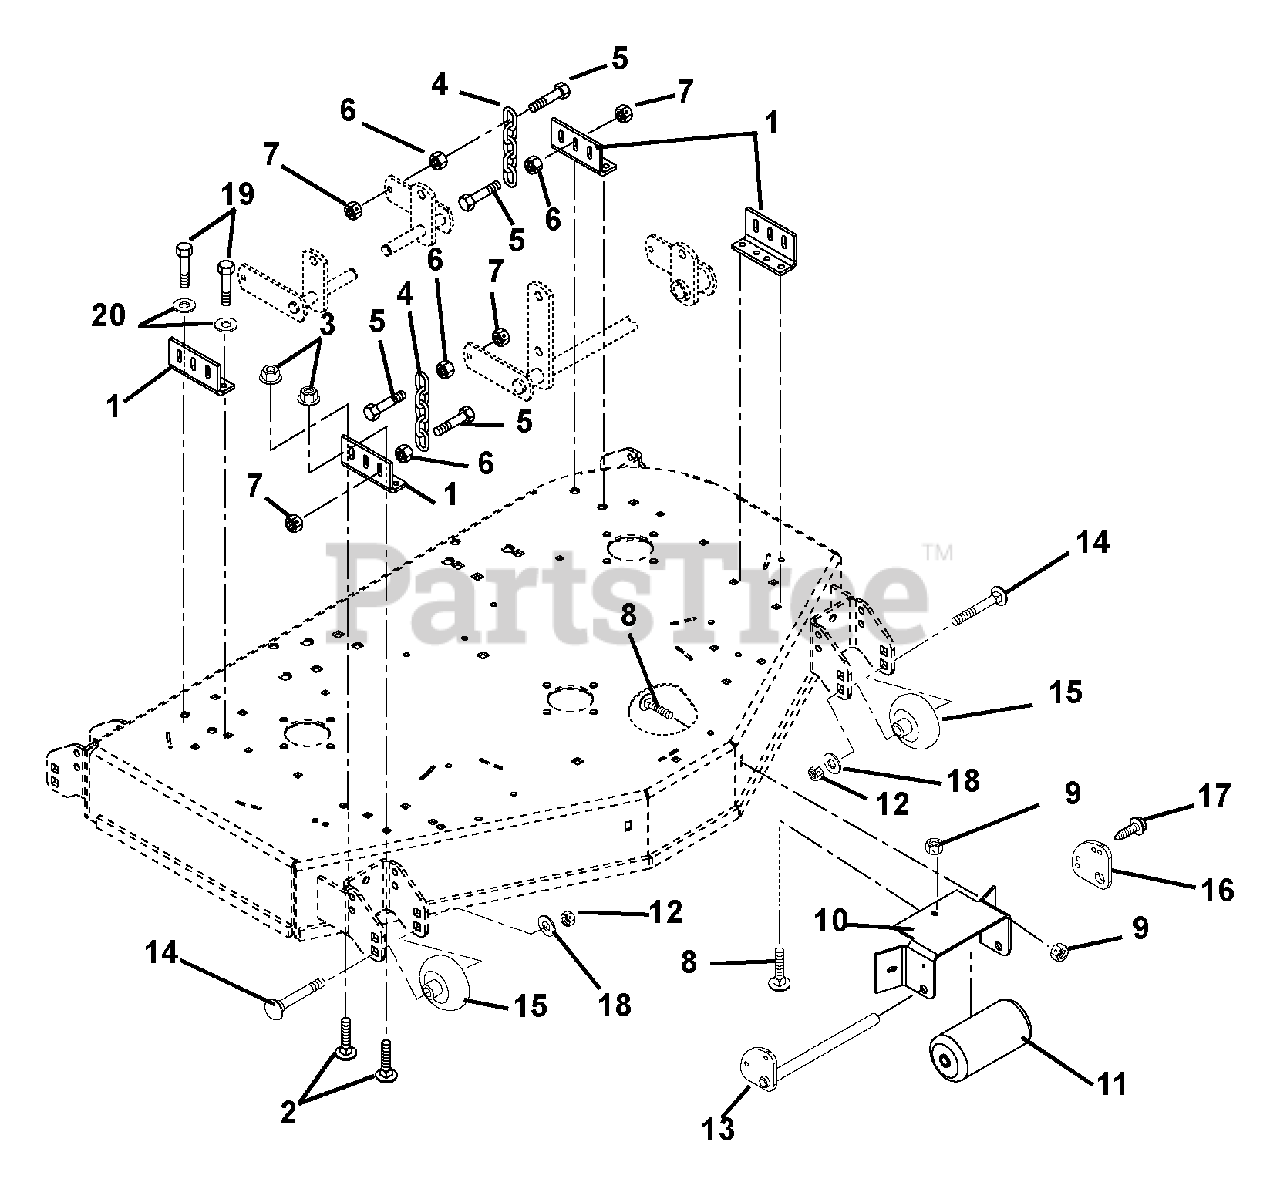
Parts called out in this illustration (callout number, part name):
1	MOWER MOUNTING BRACKET - RED
2	@BLT-RDHDSQNK .38-16X1.00 G5YZ
3	@NUT-LK-TOP-FLG .38-16 YWZC
4	CHAIN, LINK
5	BLT-HEX M12X1.75X55 GR5 YZ
6	NUT-SPNLK-FLG M12-1.75 YZ
7	NUT-LK-TOP-FLG M12-1.75 YZ
8	@BLT-RDHDSQNK .38-16X1.00 G5YZ
9	@NUT-LK-TOP-FLG .38-16 YWZC
10	BRACKET - ANTI-SCALP ROLLER
12	@NUT-LK-NYL .50-13 YWZC
13	WMT - ROLLER BRACKET
14	BLT-RDHDSQNK .50-13X5.00 GR5YZ
15	WHEEL, 3X5
16	ANTI-SCALP WASHER - RED
17	SCR-TAP.250-20X.62 HWH BLK ZC
18	@WSHR-FL-STL.531X1.06X.095YWZC
19	@BLT-HEX .38-16X1.00 GR5 YWZC
20	@WSHR-LK .38X.094 REG YWZC
